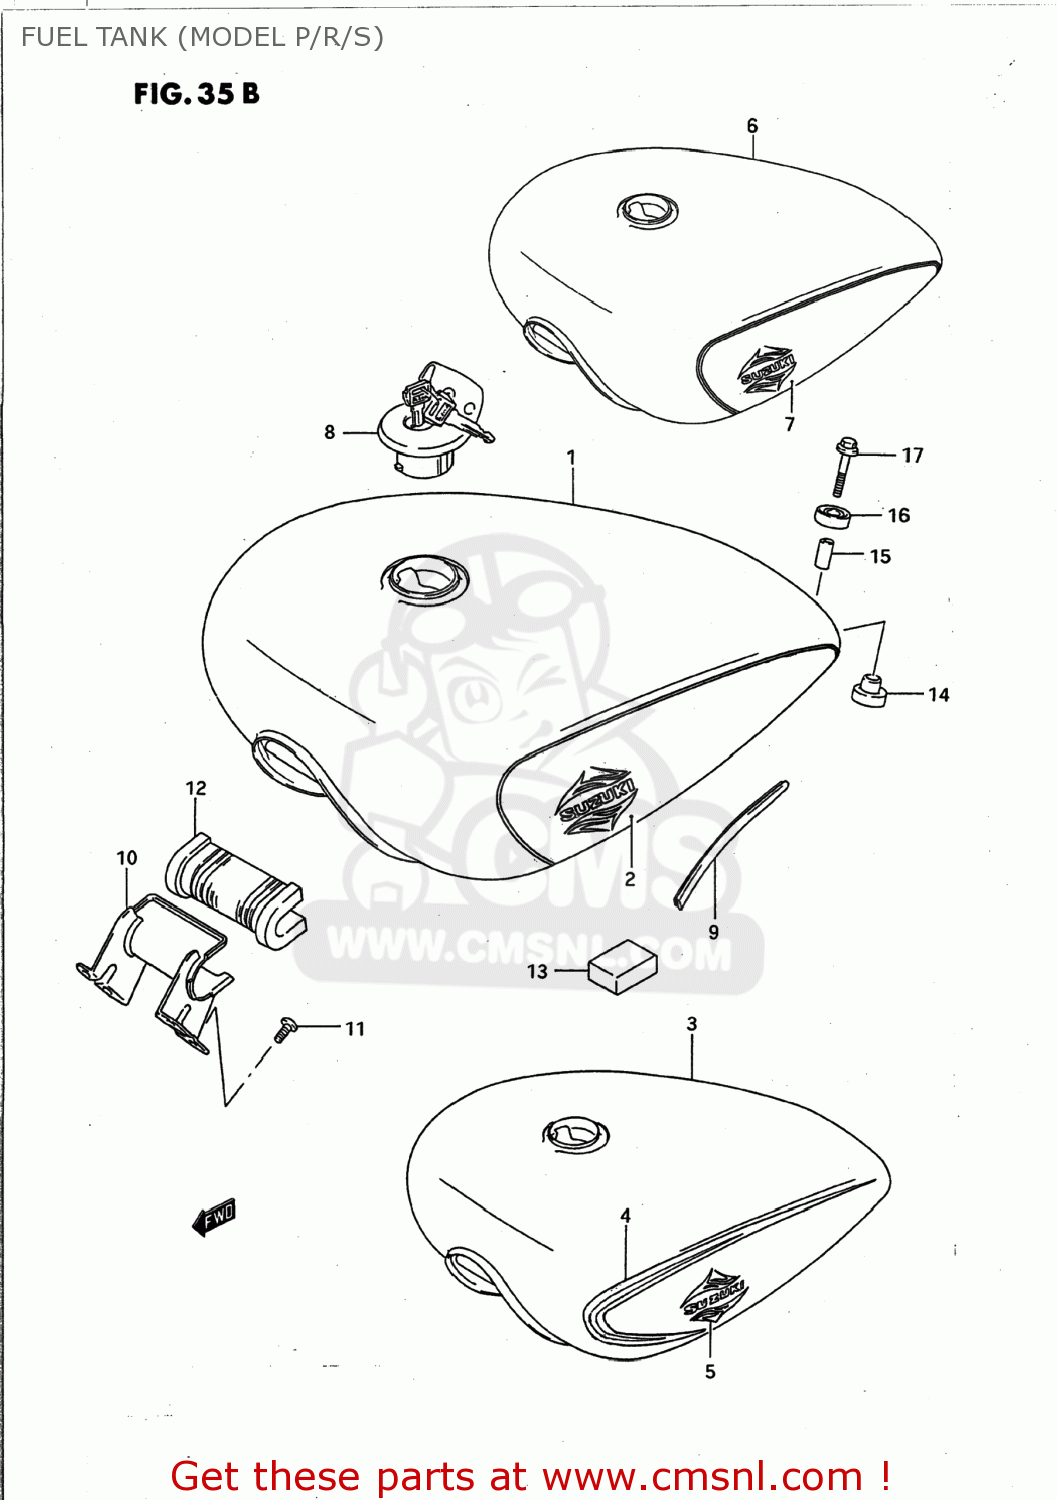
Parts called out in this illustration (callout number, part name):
1	TANK ASSEMBLY,FUEL
2	TAPE SET,FUEL TANK
3	TANK ASSEMBLY,FUEL
4	TAPE SET,FUEL TANK STRIPE
5	EMBLEM,FUEL TANK
6	TANK ASSEMBLY,FUEL
7	TAPE SET,FUEL TANK
8	CAP SET,FUEL TANK
9	MOLDING,FUEL TANK
10	BRACKET COMP,FUEL TANK
11	SCREW
12	CUSHION,FUEL TANK FR
13	CUSHION
14	CUSHION
15	SPACER
16	CUSHION
17	BOLT
